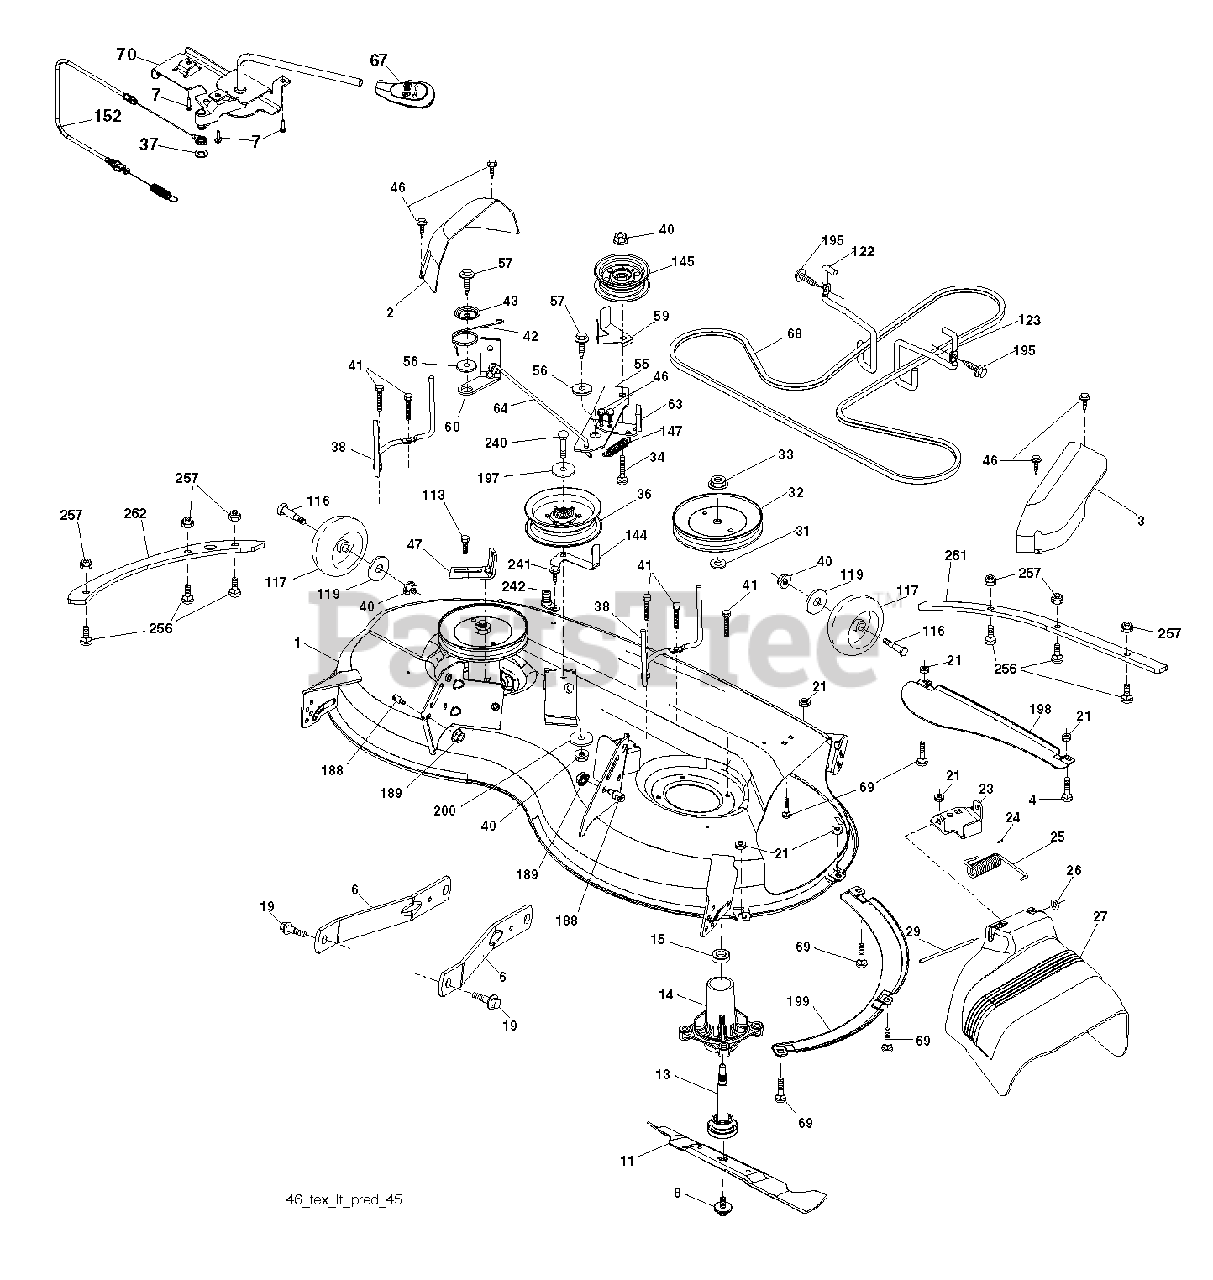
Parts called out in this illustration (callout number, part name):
1	DECK SVC 46"583900906X421
2	COVER.MANDREL.LH.46"
3	COVER.MANDREL.RH.46"
4	BOLT
6	ARM.SUSPENSION.MOWER.R
7	SCREW.#10 X 0.750.BOS (2 2)
8	BOLT.WASHER.ASM.7/16-2
11	BLADE.MOWER.46".HI.LIFT
13	SHAFT.ASM.MDRL.N/GREASE.38
14	HOUSING.MANDREL.4PT.
19	BOLT.SHOULDER
21	LOCKNUT
23	BRKT.DEFLECTOR.38"2005+
24	CAP-SLEEVE LT
25	SPRING.TORSION.DEFLECT
26	NUT PUSH M
27	SHIELD.DEFLECTOR.MOWER.46"BLAC
29	ROD.HINGE
31	WASHER.SPACER.MANDREL
32	PULLEY.MANDREL.5.438.PD
33	NUT.FLANGE.LOCK.TOP
34	BOLT.3/8-16X1.50
36	PULLEY.IDLER.2006
38	KEEPER.BELT.MANDREL.PULLEY
40	NUT LOCK FLG 3/8-16 UNC
41	Hex Washer Head Bolt, .313-18 X 1.19
42	SPRING.TORSION.BRAKE
43	SRPING.TORSION.RETAINE
46	SCREW.1/4-20X5/8
47	BRKT.CLUTCH.CABLE
55	IDLER.ARM
56	SPACER.RETAINER
57	SCREW 3/8-16X1
59	GUARD, BELT
60	ARM BRAKE MOWER RH 38"
64	LINKAGE BRAKE
67	HANDLE.CLUTCH.CABLE.LT
68	V-BELT
69	BOLT
70	CLUTCH.ASM.MANUAL.YT.PREDATORQ
113	BOLT.5/16HEX.WHS.HD
116	BOLT M
117	WHEEL.GAGE.HALF.SPOKED
119	WASHER
122	KEEPER BELT ENGINE LH
123	KEEPER BELT RH
144	KEEPER.BELT.MOWER
145	PULLEY.IDLER.48"PRIMARY
147	SPRING RETURN
152	CABLE.MECHANICAL.CLUTCH
188	STUD.FASTNER.W/ANTI-ROTATE
189	NUT LOCK HEX FLANGE 5/16-18
195	SCREW, 3/8-16X3/4
197	WASHER
198	BAFFLE CENTER FRONT
199	BAFFLE FRONT RH
200	WASHER.13/32 X 1 X 1/2.11GUARD
240	BOLT-HEX EAK
241	SCREW.TT.#10-32X.5.3/8.FLANGE
242	PORT.WASHOUT
256	Buttonhead Screw, 5/16-18
257	NUT T
261	Deck Reinforcement Plate, 46 F
262	Side Reinforcement Plate, 46" Bolt-on
